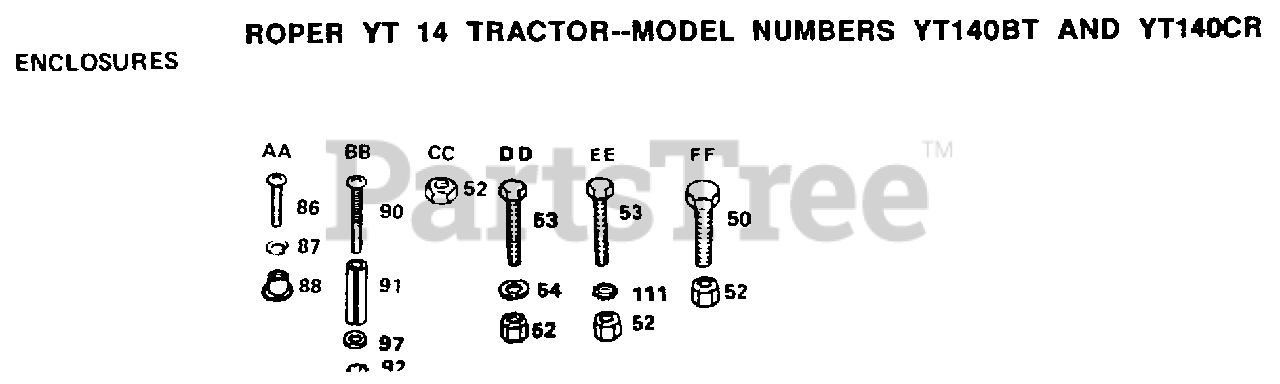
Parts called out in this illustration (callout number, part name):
53	BOLT
54	WASHER
86	SCREW
87	LOCKWASHER
88	WELDNUT
90	SCREW
91	SPACER LT
97	WASHER
111	LOCKWASHER
